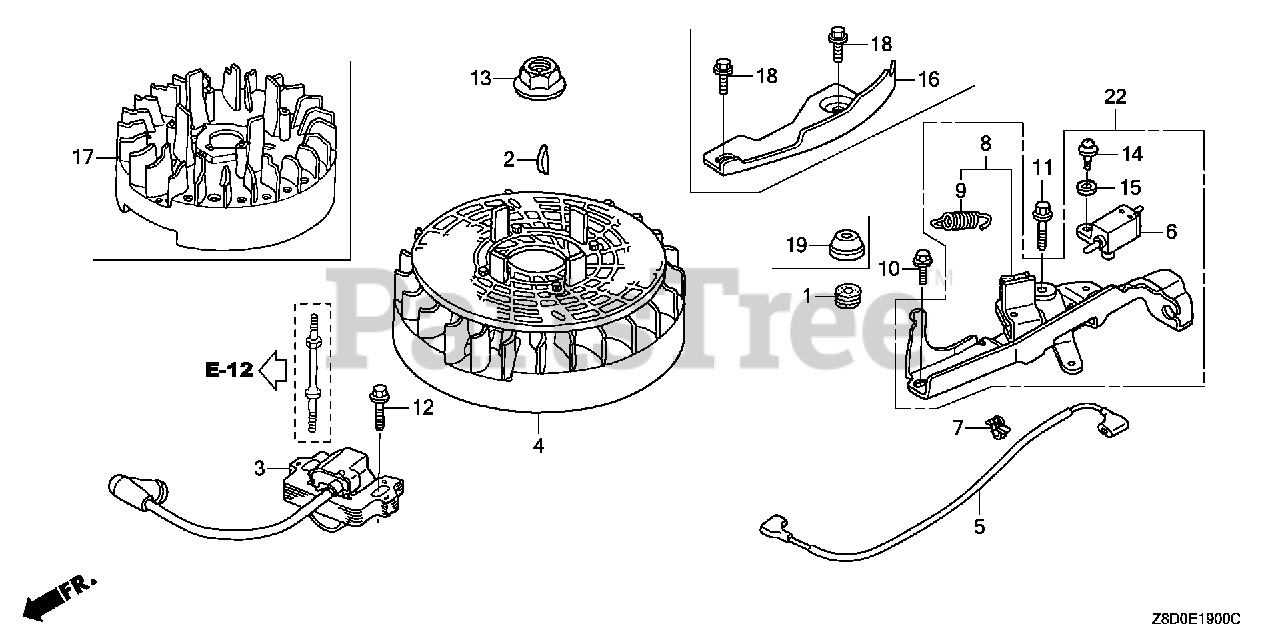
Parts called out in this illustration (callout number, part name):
2	KEY, SPECIAL WOODRUFF (25X18)
3	COIL ASSY., IGNITION (USE FOR F/W OF TEC) (TEC) Use up to Engine SN 3747197.
3	COIL ASSY., IGN
3	COIL ASSY., IGNITION (PHELON)
4	FLYWHEEL ASSY. (TEC) (USE FOR IGN. COIL OF TEC)
5	WIRE, STOP SWITCH
6	SWITCH ASSY., ENGINE STOP (Honda Code 5580683). (N.C)
7	HOLDER, WIRE (FASTEX)
7	CLIP, CABLE (A)
8	BRAKE ASSY.
8	BRAKE SUB-ASSY.
9	SPRING, BRAKE LEVER
10	BOLT, FLANGE (6X14)
11	BOLT, FLANGE (6X23)
12	BOLT, FLANGE (6X23)
13	NUT, FLANGE (14MM)
14	SCREW-WASHER (4X12)
15	WASHER, PLAIN (4MM)
22	BRAKE ASSY.
